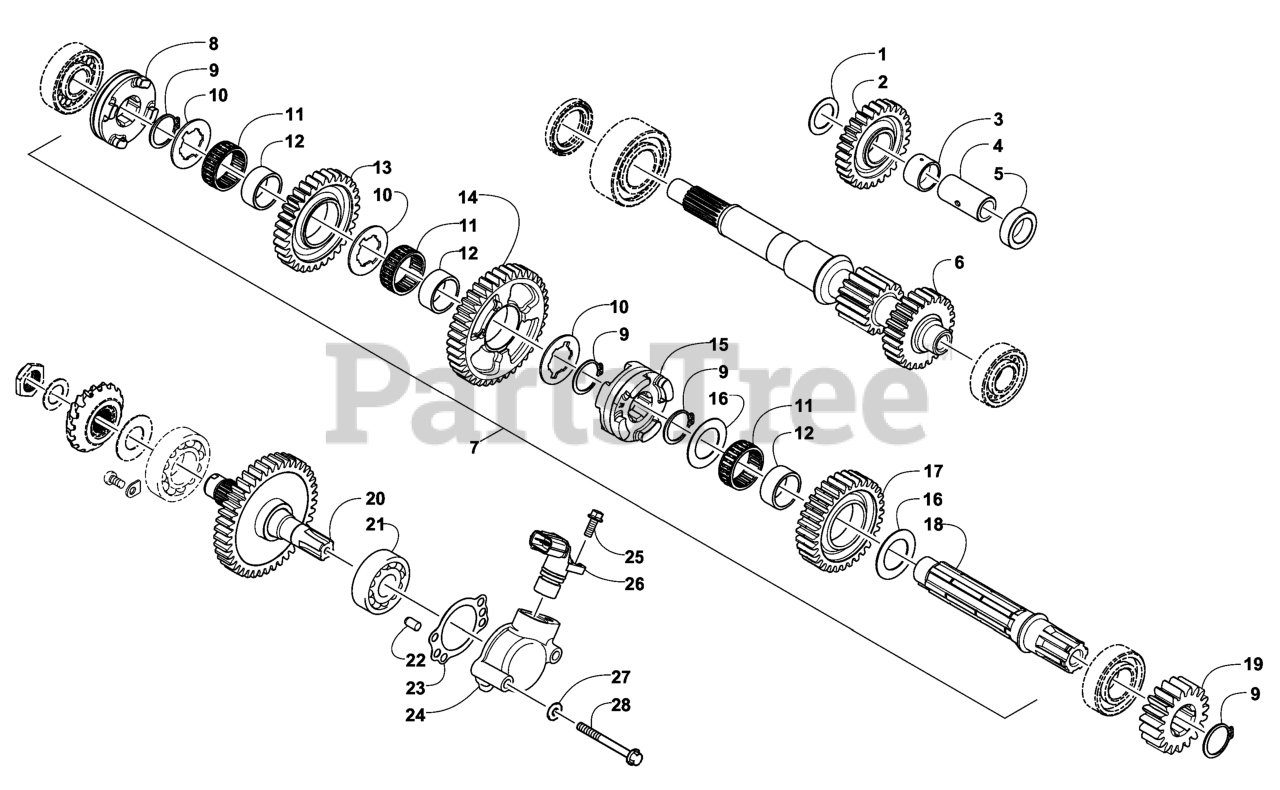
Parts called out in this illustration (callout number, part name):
1	WASHER-THRUST
2	GEAR-REVERSE IDLE, 28T
3	BUSHING-GEAR, REVERSE IDL
4	SHAFT-REVERSE IDLER
5	SPACER-REVERSE IDLE GEAR
6	SHAFT-DRIVE
7	COUNTER SHAFT ASM
8	SHIFT-BACKWARD
9	CLIP-CIR
10	WASHER-SPLINE
11	BEARING-NEEDLE, ROLLER
12	BUSHING
13	GEAR-DRIVEN, BACKWARD (32
14	GEAR-DRIVEN, LOWER (40T)
15	SHAFT-FORWARD, LOW
16	WASHER-THRUST
17	GEAR-DRIVEN, FORWARD (32T
18	COUNTERSHAFT
19	GEAR-DRIVEN, NO. 2
20	SHAFT-OUTPUT
21	BEARING-BALL, RADIAL
23	GASKET-SPEEDO
24	HOUSING-SPEEDO SENSOR
25	BOLT-FLANGE
26	SENSOR-SPEED
27	SEAL-FASTENER
28	BOLT-FLANGE
